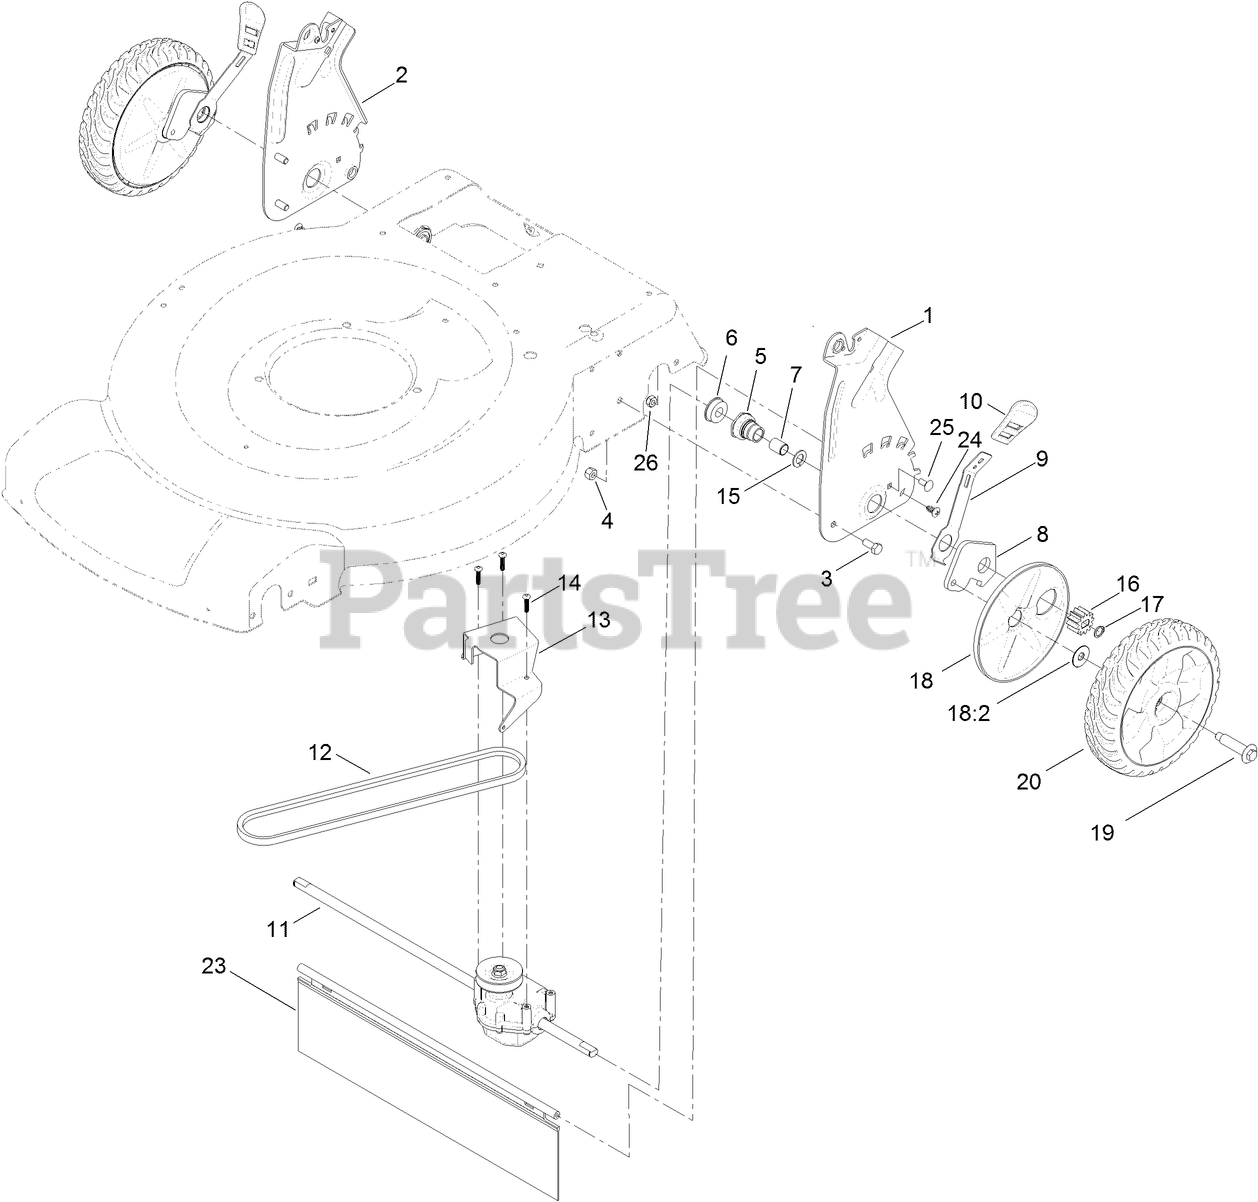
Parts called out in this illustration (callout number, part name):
1	PLATE-REAR, LH (HOC)
2	PLATE-REAR, RH (HOC)
3	SCREW-HH
4	NUT-LOCK, NI
5	RETAINER-BUSHING, HOC
6	BEARING-BALL
7	BUSHING-SLEEVE
8	ARM-PIVOT, REAR
9	ARM-SPRING
10	KNOB-HOC
11	TRANSMISSION ASM
12	BELT-V
13	BRACKET-TRANSMISSION
14	SCREW-PLASTITE
15	WASHER-THRUST
16	GEAR-PINION, 15T
17	RING-RETAINING
18	WHEEL COVER ASM
18:2	WASHER-STEPPED
19	BOLT-SHOULDER
20	8 INCH WHEEL GEAR ASM
23	SHIELD-TRAILING
24	SCREW-PTH
25	SCREW-CARR
26	NUT-LOCK, NI
